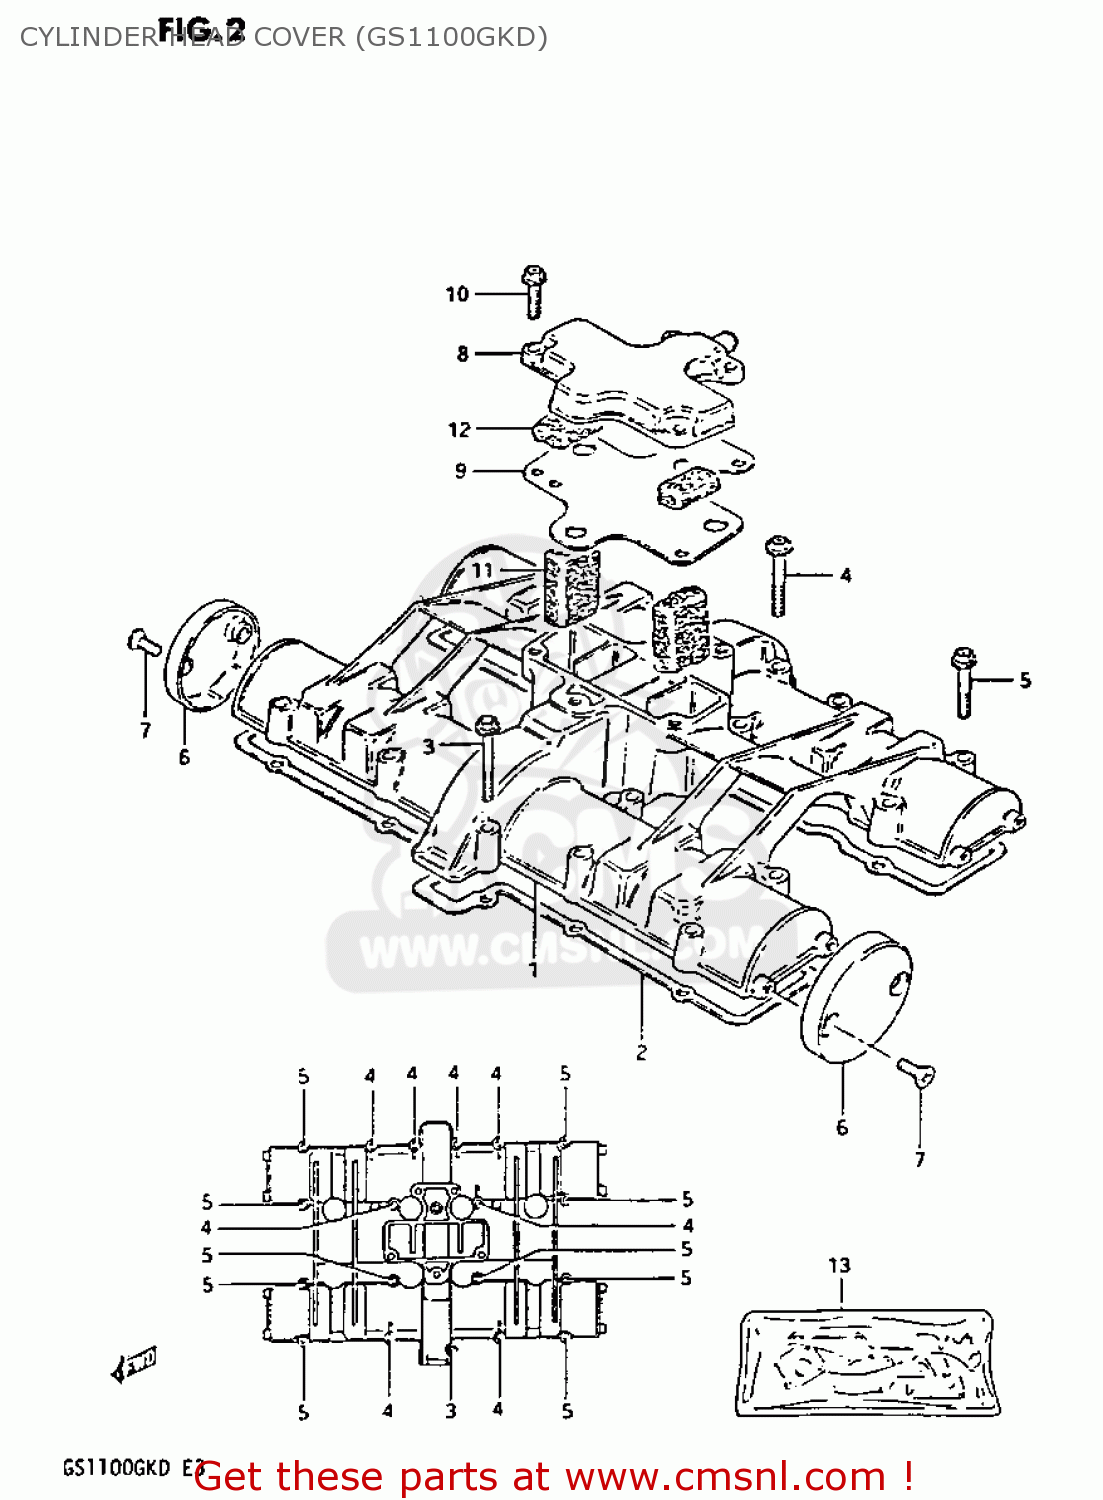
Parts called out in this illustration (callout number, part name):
1	COVER,CYLINDER HEAD
2	GASKET,CYL HEAD COVER (NAS)
3	BOLT (6X45)
4	BOLT
5	BOLT 6X35
6	CAP,CYLINDER HEAD COVER
7	SCREW(5X12)
8	COVER,BREATHER
9	GASKET (MCA)
10	BOLT 6X20
11	COVER,BREATHER
12	SEPARATOR,OIL BREATHER
13	GASKET SET
